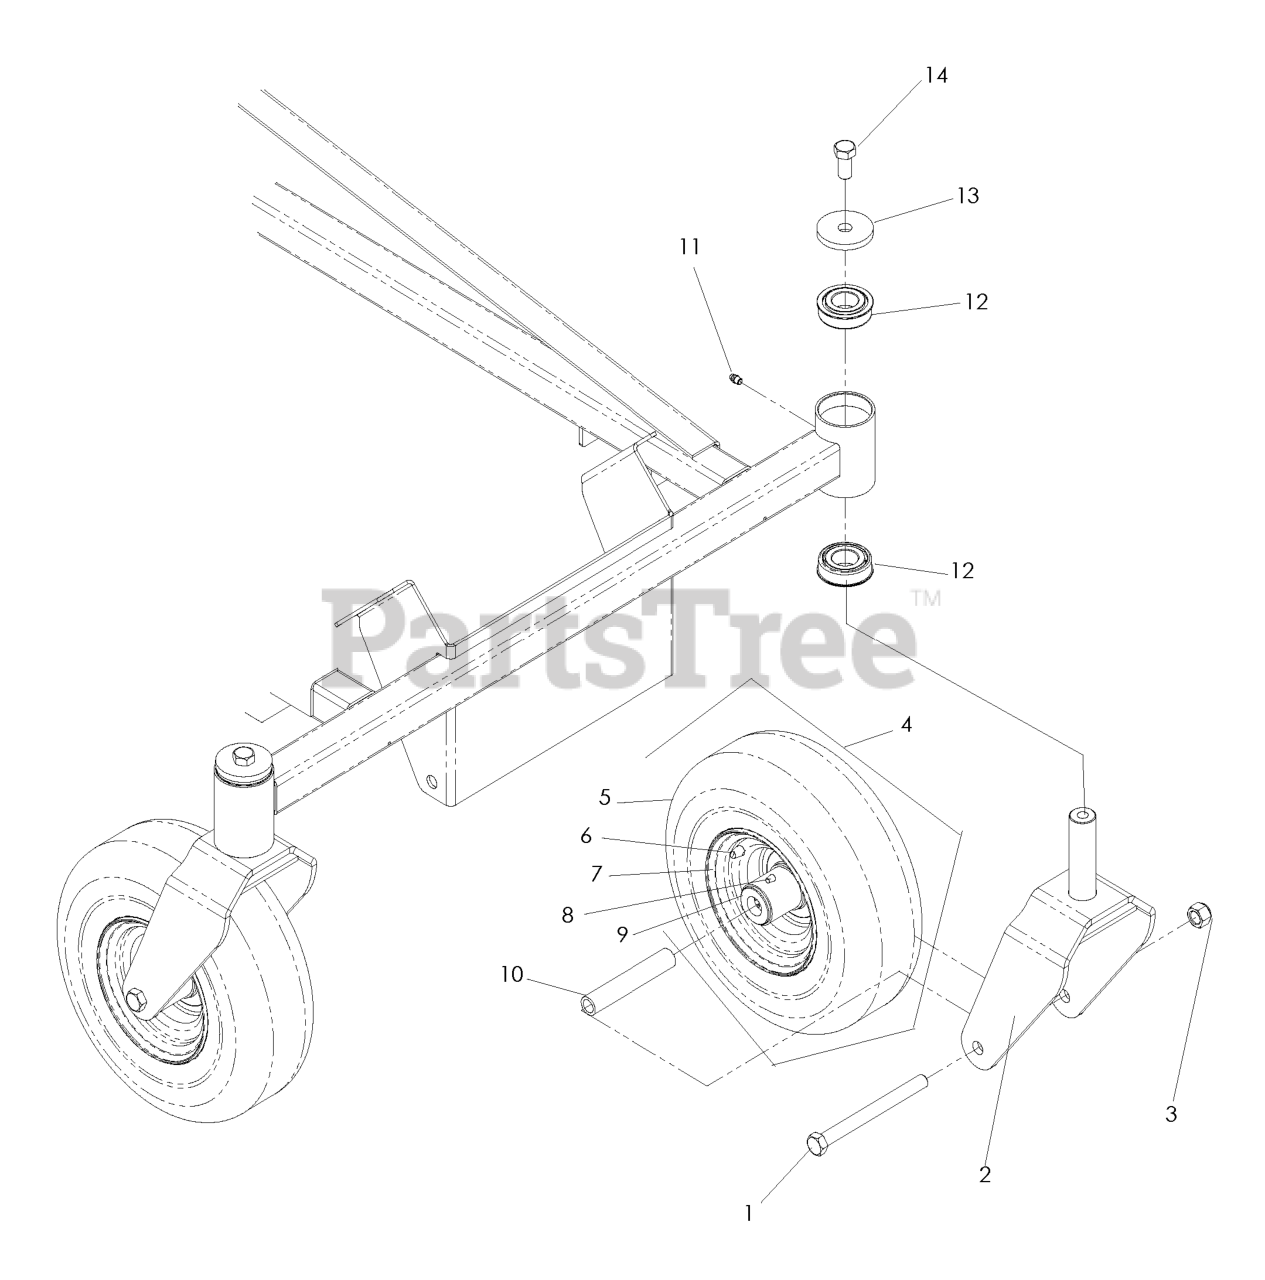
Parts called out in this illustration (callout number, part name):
1	HCS 1/2C X 5 1/2
2	CASTER YOKE - PAINTED
3	NUT 1/2-13 HEX NYLOC ZD
4	TIRE/WHEEL.CASTER
5	TIRE - CASTER
6	VALVE STEM TR-412
8	ZERK
9	BEARING RETAINER
11	ZERK
12	BEARING FLANGED
13	HEAVY WASHER
14	HHCS 1/2-13 X 1
